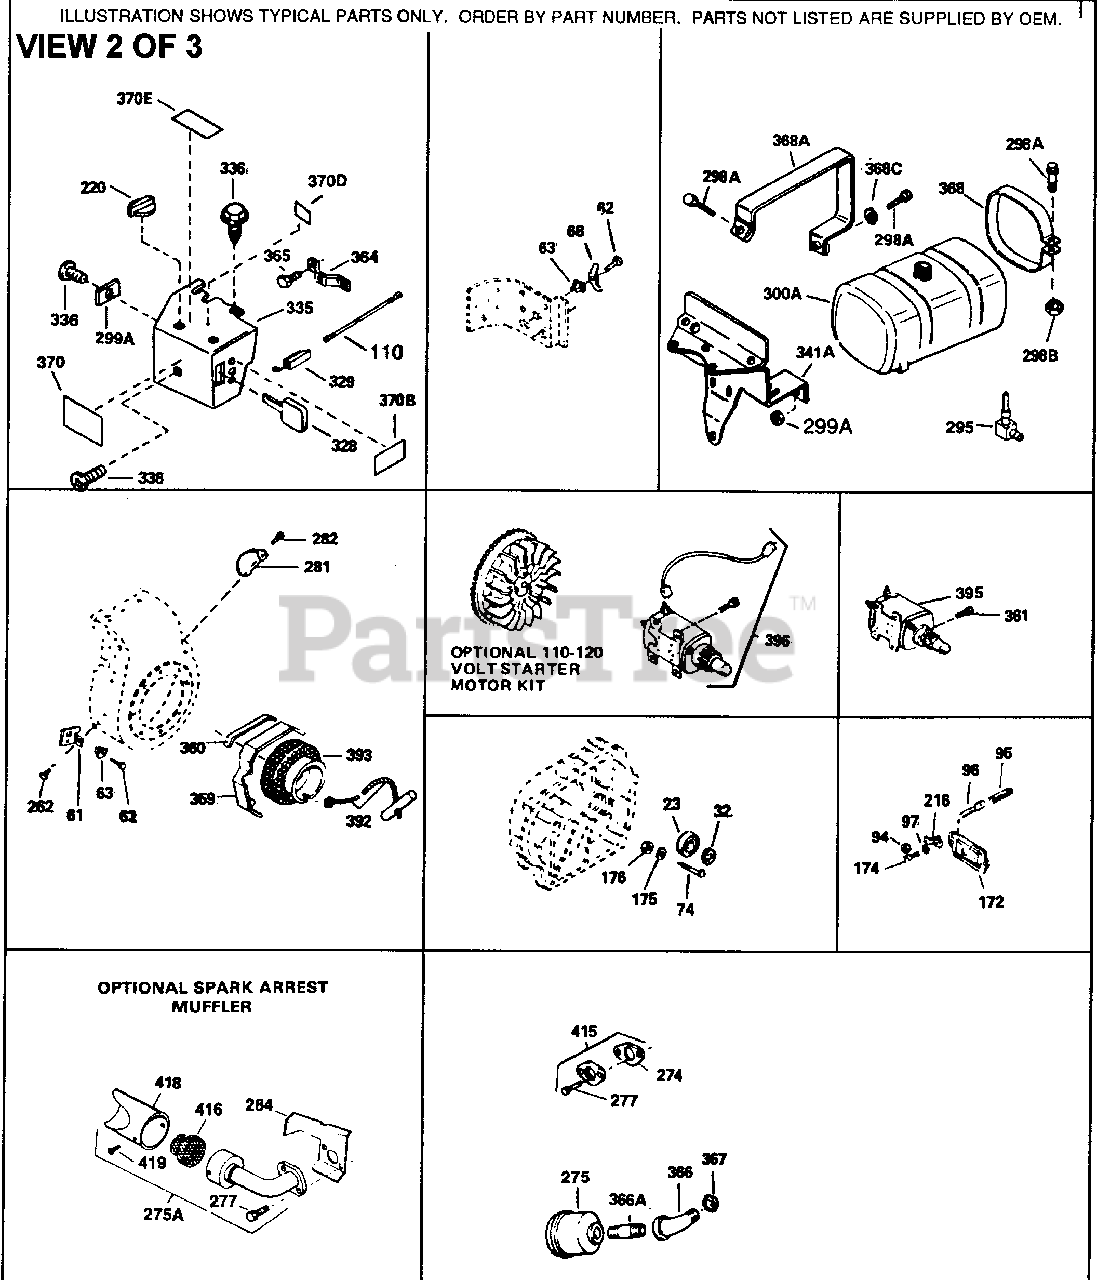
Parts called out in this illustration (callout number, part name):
23	Ball Bearing
74	Bearing Retainer
110	Ground Wire
129	Screw, 5/16-18 x 2"
172	Valve Cover
174	Screw, 10-24 x 1/2"
175	Lock Washer
176	Lock Nut, 10-24
220	Control Knob
228	# Stud, 1/4-20 x 6.20
229	# Nut & Lock Washer, 1/4-20
235	Air Cleaner Elbow Fitting
242	# Air Cleaner Base
260	Blower Housing
262	Screw, T-40, 5/16-24 x 21/32"
269	* Exhaust Manifold Gasket
275	Muffler
366	Muffler Elbow
366A	Muffler Nipple
367	Lock Nut
370	Instruction Decal
370B	Instruction Decal
370D	Throttle Decal
